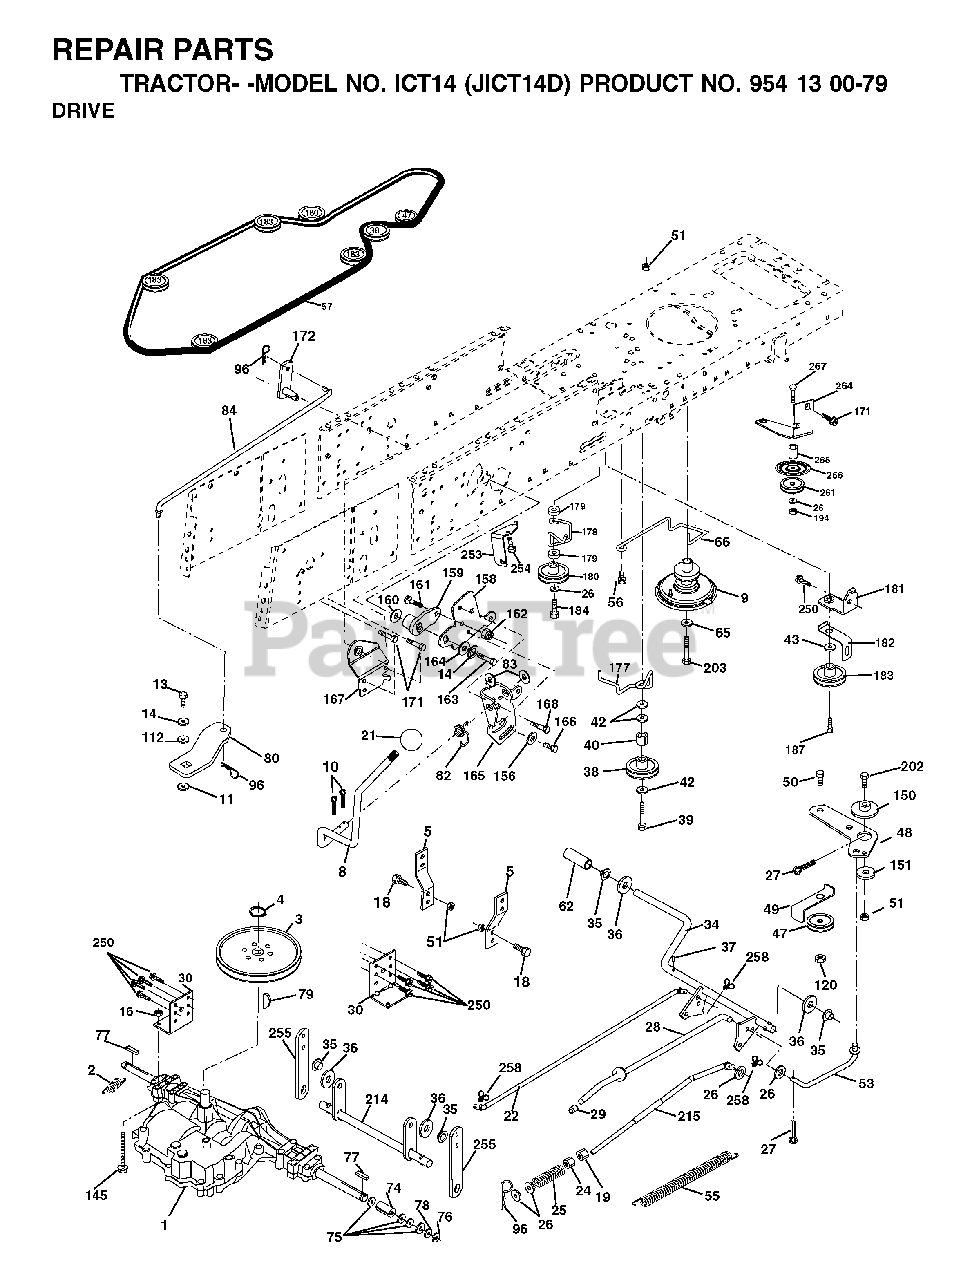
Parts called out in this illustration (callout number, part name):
2	SPRING,BRAKE RETURN
4	RETAINING RING LT
5	STRAP TORQUE
8	ROD SHIFT
10	PIN COTTER
11	WASH-SHFT PLT LT
13	BOLT 1/4-28X3/4
14	LOCKWASHER
16	NUT.71038.31-18.HEX.NYLOCK
19	NUT
21	KNOB T (1/2-HOLE)
24	NUT
25	SPRING ROD LT
27	COTTER PIN
28	ROD, PARKING BRAKE
29	PLUNGER CAP
30	BRKT, MOUNT TRNSAXLE
34	SHAFT, FOOT PEDAL
35	BEARING.NYLON
36	WASHER LT
37	DRIVE PIN
38	PULLEY.FLAT
42	WASHER
47	IDLER PULLEY
48	BELLCRANK, CLUTCH
49	RETAIN BELT
50	BOLT
51	LOCKNUT
53	LINK, CLUTCH LT
55	SPRING, RETURN LT
56	SCREW.3/8-16
57	V-BELT.KEV.111"
62	PEDAL COVER T
65	LOCKWASHER
66	KEEPER BELT ENGINE
74	SPACER AXLE
76	E-RING LT
77	SQUARE KEY
80	ARM SHIFT
82	SHIFT SPRING
83	WASHER
96	RETAINER M
112	WASHER LT
120	NUT LOCK FLG 3/8-16 UNC
150	BUSHING.BELLCRANK.GRD.DR
151	WASHER 12/32X2X10GA
156	WASHER.SRRTD.5/16
158	BRACKET
159	HUB
161	BOLT
162	NUT.CROWNLOCK.1/4
165	RP BRACKET
167	BRACKET
168	BOLT.SHOULDER.5/16-18X
180	PULLEY.FLAT.IDLER
184	SCREW.HXWSH.3/8
187	BOLT.5/16-18X1.25
202	BOLT
250	SCREW 3/8-16X3/4
258	CLIP RETAINER
261	FLAT IDLER PULLEY
265	SPACER IDLER
